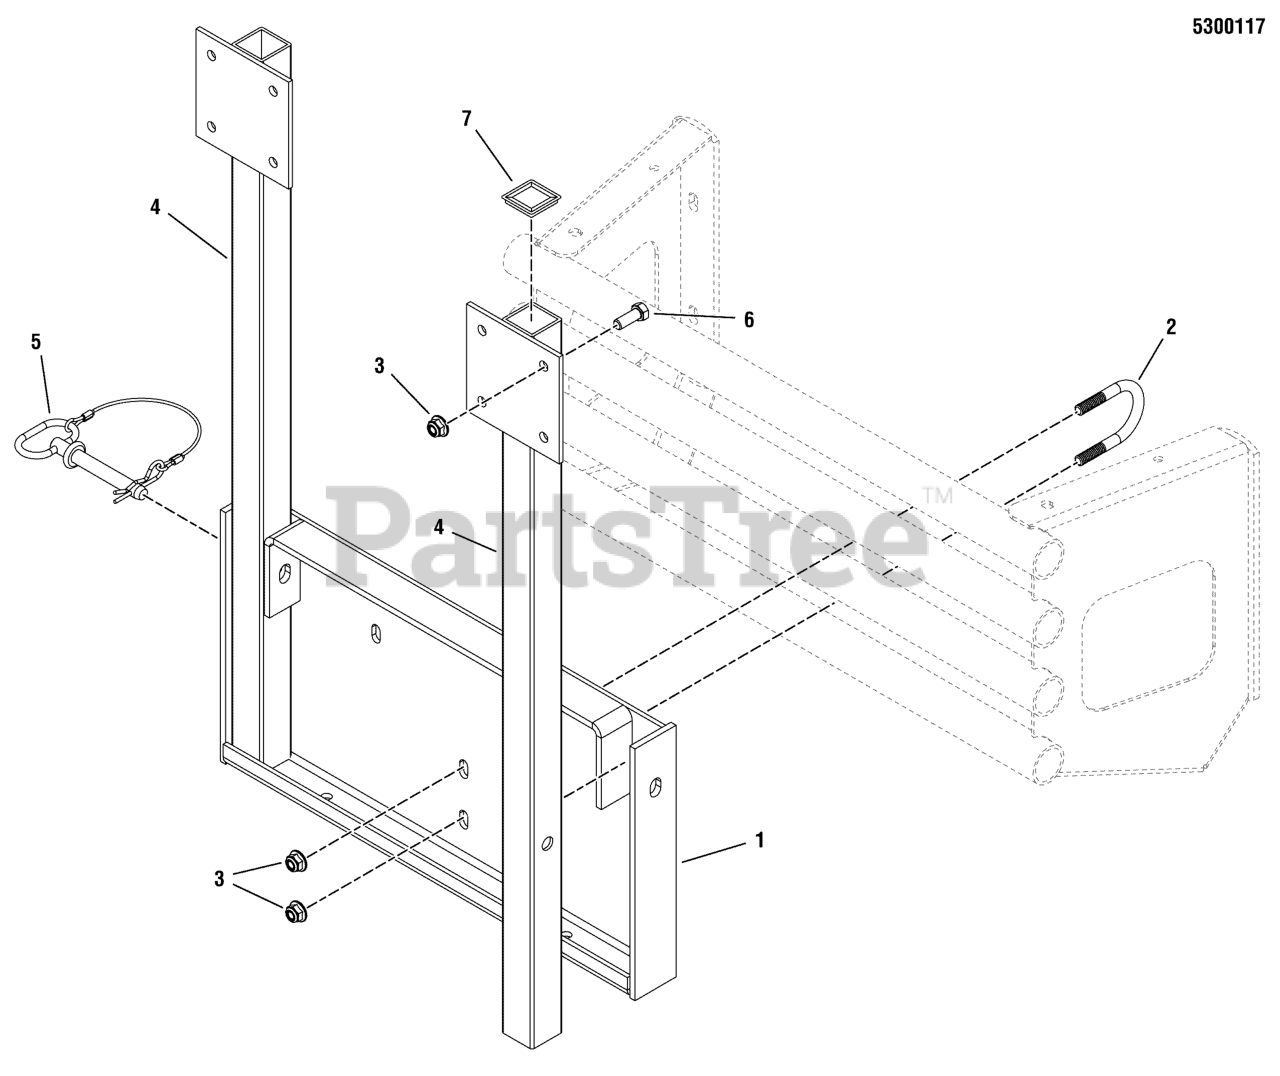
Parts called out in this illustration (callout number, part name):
1	WELD, BAGGER MOUNT, IS3100Z - BLK
2	U-BOLT, 3/8 X 1-1/4
3	NUT, 3/8-16 HEX NYLOCK FLANGE
4	WELD, MOUNT, POST - BLK
5	PIN, HITCH, .50 X 3.25 W/ LAY
6	BOLT, 3/8-16 X 1" GD5 CZ
7	CAP, PLASTIC, 1-1/2 X 1-1/2
